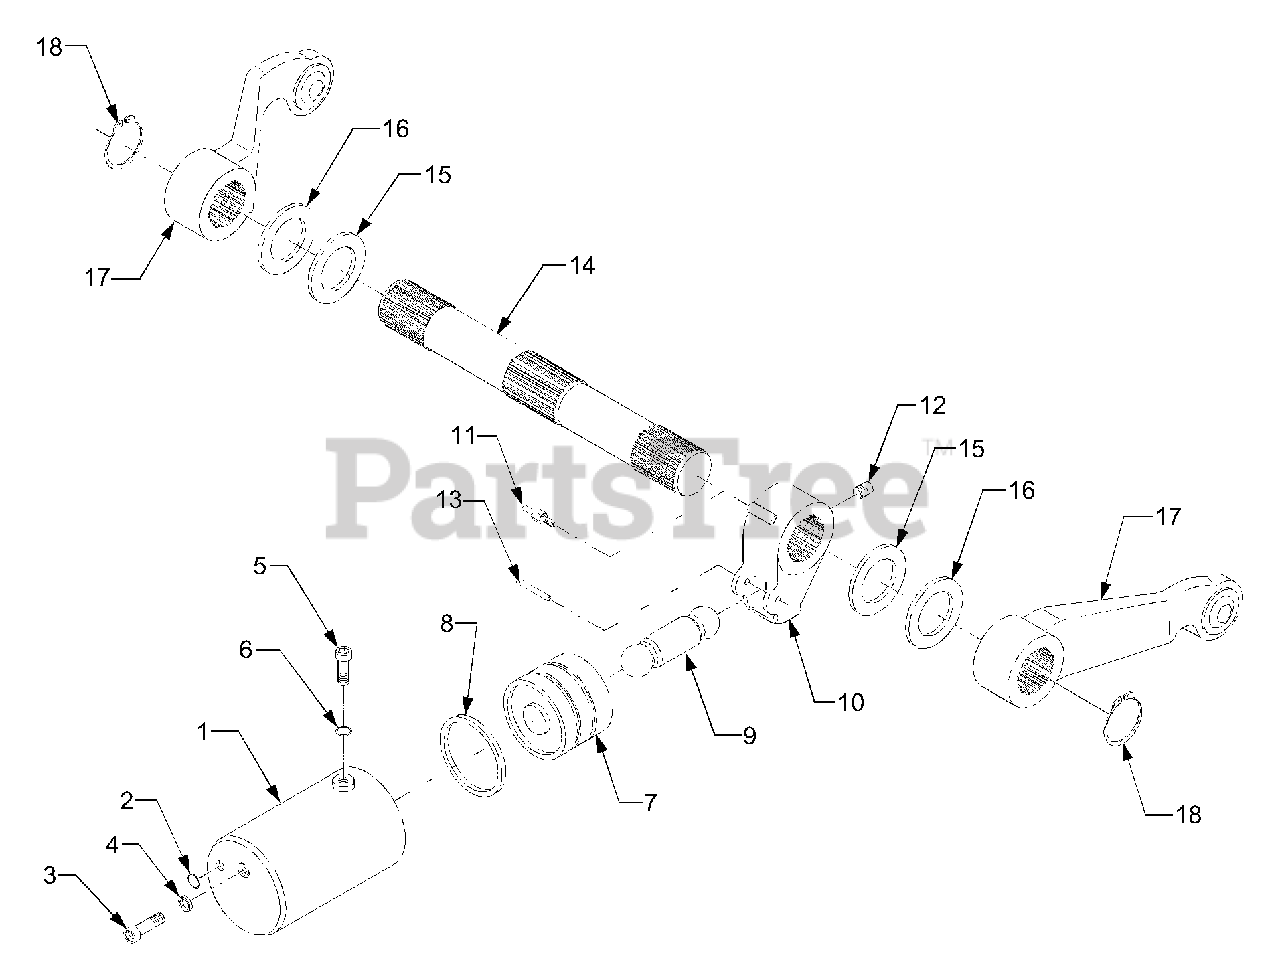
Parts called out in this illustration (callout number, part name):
9	Rod, Hydraulic
10	Arm, Hydraulic
14	Shaft, Hydraulic Arm
17	Lift Arm Ass'y
